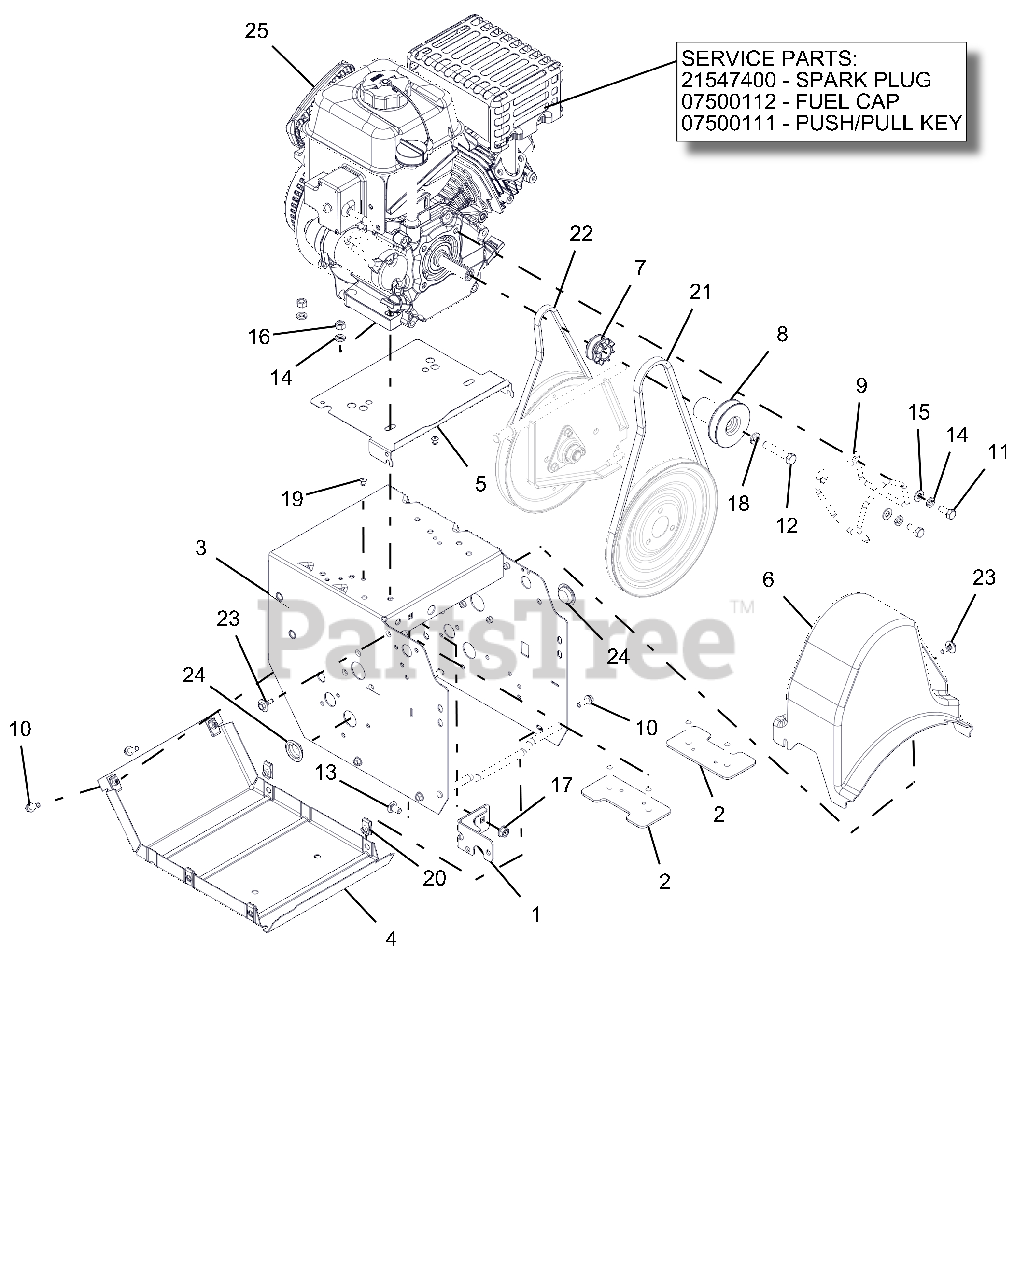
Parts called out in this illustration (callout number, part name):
1	WELDMENT, FRAME BRACKET
2	STRAP, ENGINE BOLT-WELDMENT
3	WELDMENT,FRAME 920
4	COVER, BOTTOM
5	BAFFLE,ENGINE,SMALL BLOCK
6	COVER, COMPACT BELT
7	SHEAVE, TRACTION
8	SHEAVE,AUGER 3/4" PM
9	FINGER, BELT
10	BLT-HEX .25-20X.75 HWH YZ GR5
11	BLT-HEX .31-24X.75 YWZC GR5
12	BLT-HEX .38-24X2.0 YWZC
13	@BLT-RHDSSQNK .31-18X.62 G5YZ
14	WSHR-LK .312X.097 HVY YWZC
15	@WSHR-FL-STL.344X.688X.065YWZC
16	@NUT-HEX .31-18 YWZC
17	@NUT-LK-TOP-FLG .31-18 YWZC
18	@WSHR-LK .38X.094 REG YWZC
19	RVT-POP .187 YZ
20	NUT-RTNR .25-20X.56
21	V-BELT, HA-RAW EDGE
22	V-BELT, 3L-WRAPPED
23	SCR-TAP .25-20X.5 CAPTIVE
24	PLUG, HOLE - 1.00" FLEXTEMP
25	ENGINE, ARIENS AX208 240V/60W
25	PLUG, SPARK
25	CAP, FUEL TANK BLACK
25	KEY, PUSH/PULL LCT (2/PACKAGE)
